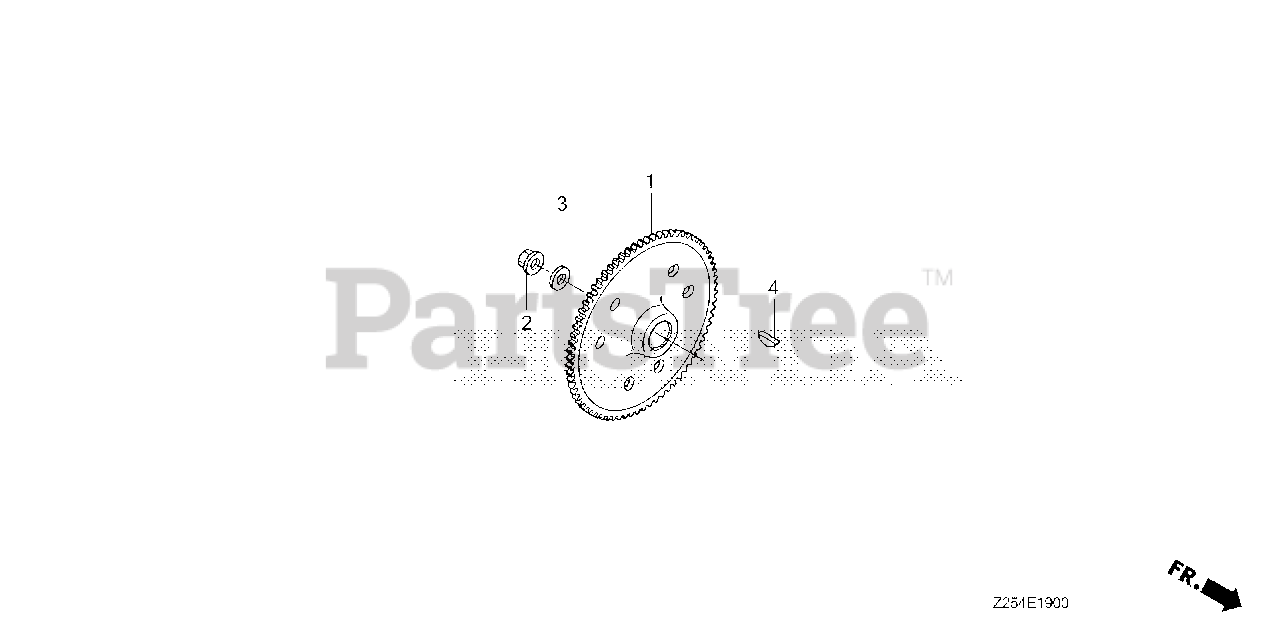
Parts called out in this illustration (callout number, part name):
2	NUT, SPECIAL (16MM)
3	WASHER, FLYWHEEL
4	KEY, SPECIAL WOODRUFF (25X18)
